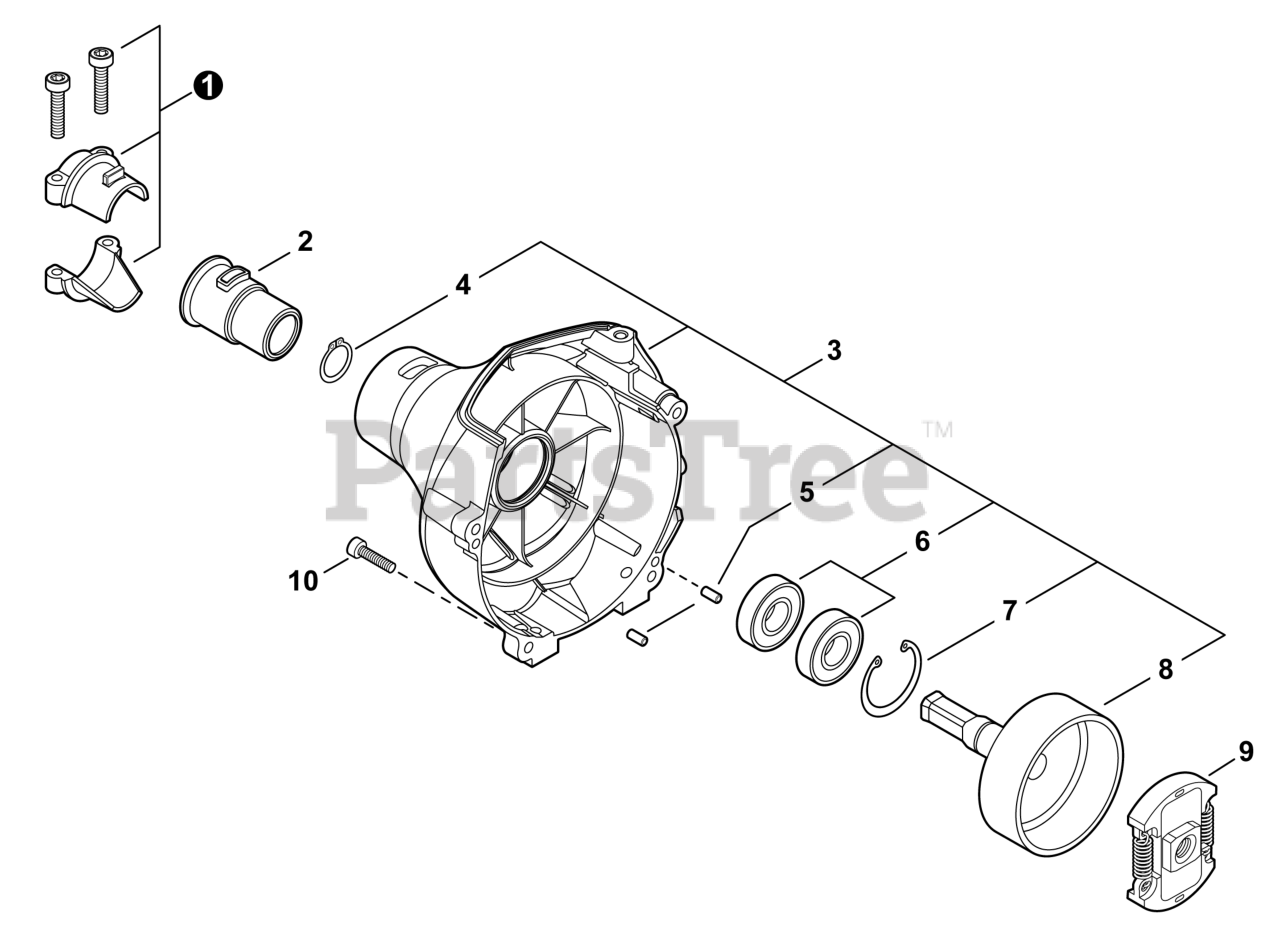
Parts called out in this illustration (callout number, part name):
1	HOLDER KIT
2	CUSHION 25
3	COVER ASSY, FAN
4	RING, SNAP 12
5	PIN, LOCATING 4
6	BEARING, BALL 6001
7	RING, SNAP 28
8	DRUM, CLUTCH
9	CLUTCH ASSY
10	BOLT, TORX 4x16
